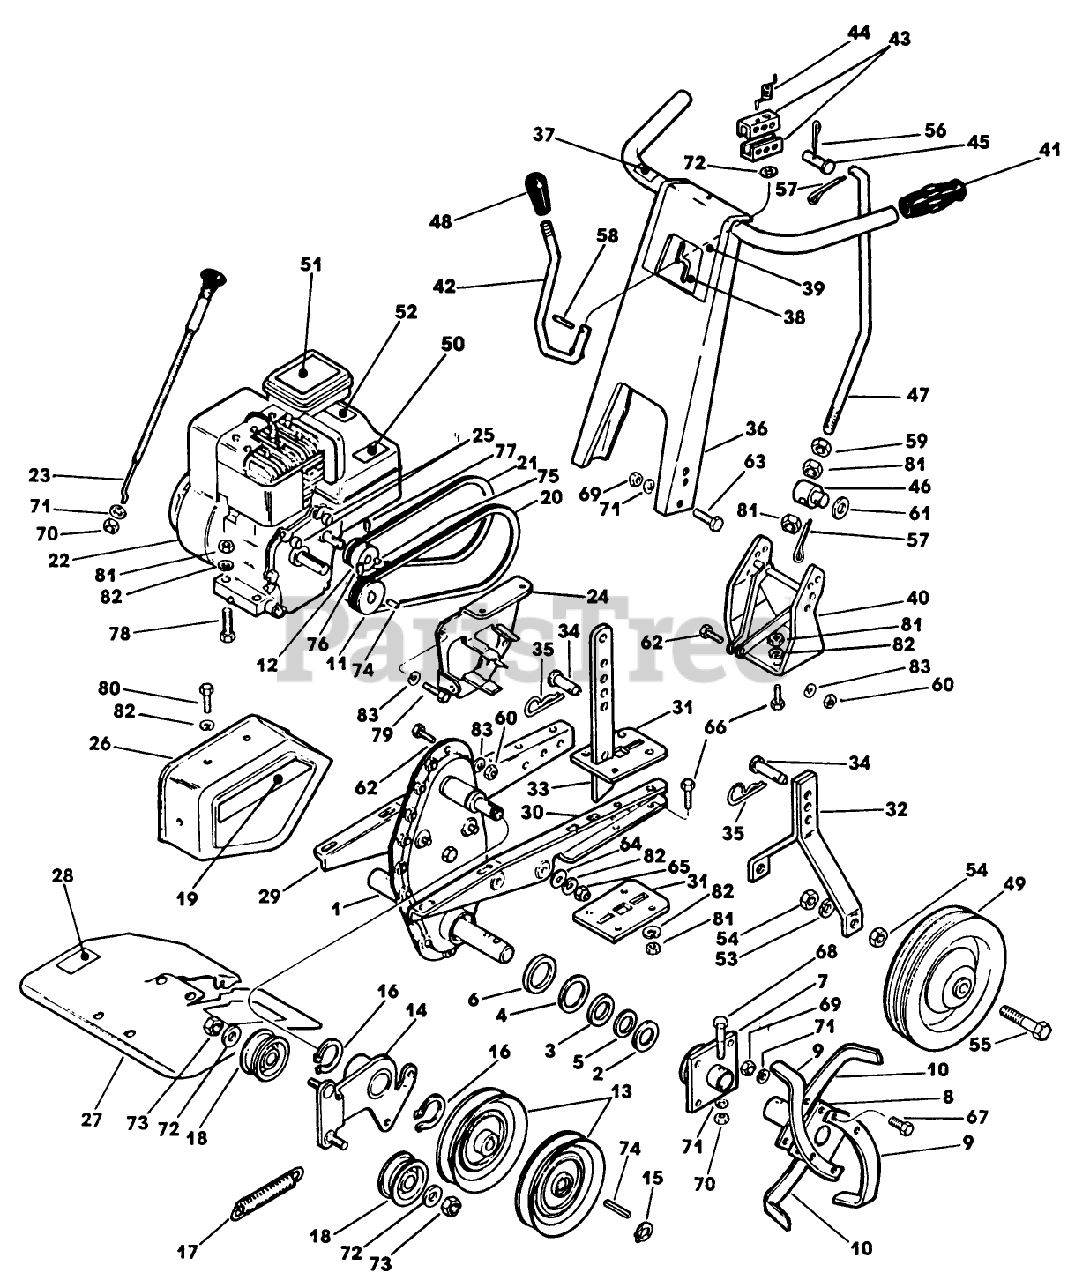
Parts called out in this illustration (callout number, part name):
1	CHAINCASE SER. KIT
3	SEAL-FELT
4	SEAL - FELT
5	WASHER
6	WASHER BACK-UP
7	TINE HUB AY
9	TINE - RH
10	TINE - LH
14	ARM ASSEMBLY
15	RING-RETAINING
17	SPRING-DRIVE
20	V-BELT (207159)
23	THROTTLE CONTROL
33	DEPTH CONTROL
35	PIN - SPRING CLIP
40	SUPPORT AY-HANDLE *B
44	SPRING CONTROL LEV
49	WHEEL & TIRE ASM
60	NUT
65	NUT
66	SCREW - HEX
69	NUT
71	WASHER
72	WASHER
73	NUT
75	Key, Woodruff
76	SET SCREW
81	NUT SS
